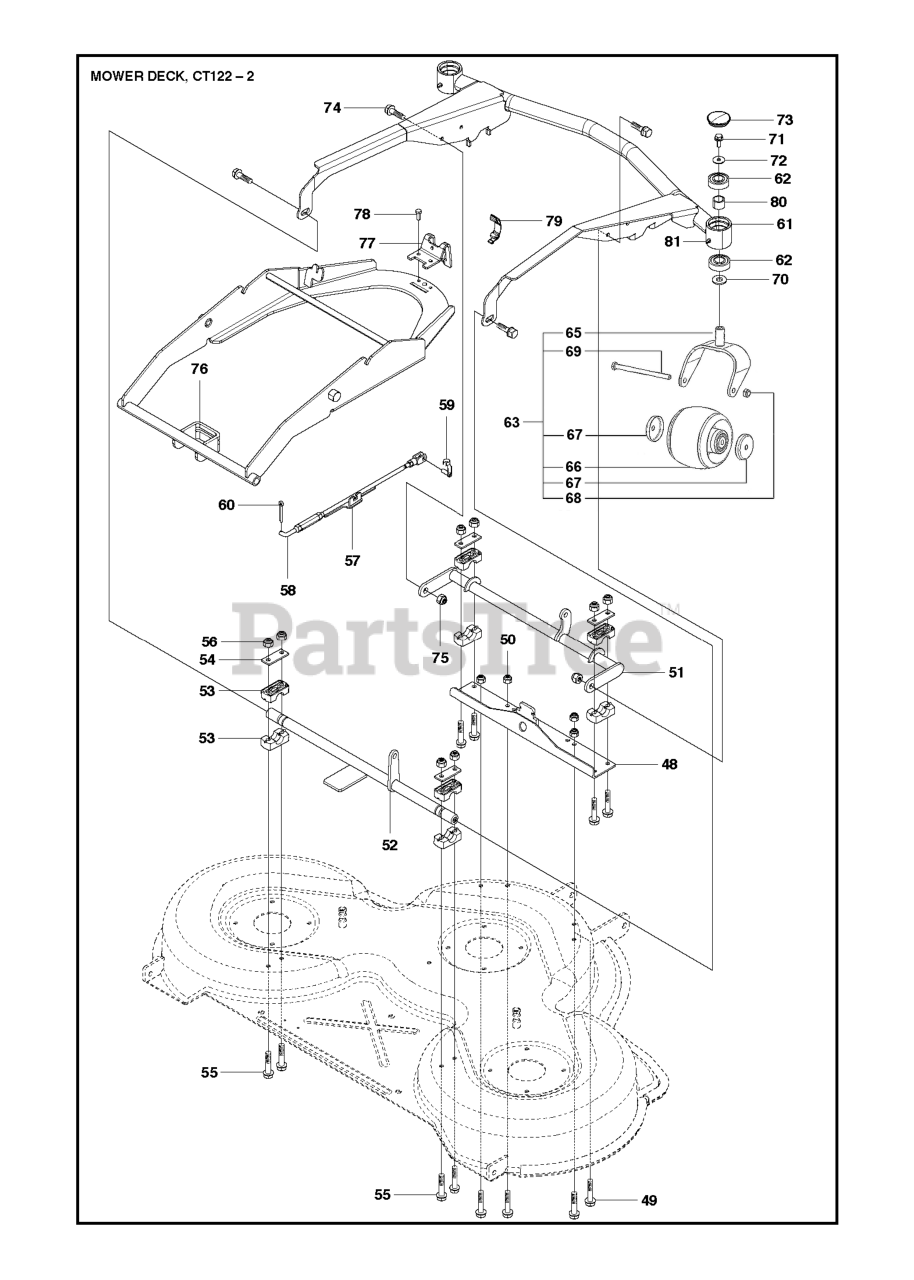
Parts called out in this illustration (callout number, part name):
50	LOCKNUT M8
56	LOCKNUT M8
58	PARALLEL ROD
72	SPACER
73	HUB CAP PIVOT WHEEL
75	LOCKNUT M8
78	SCREW
81	GREASE NIPPLE
